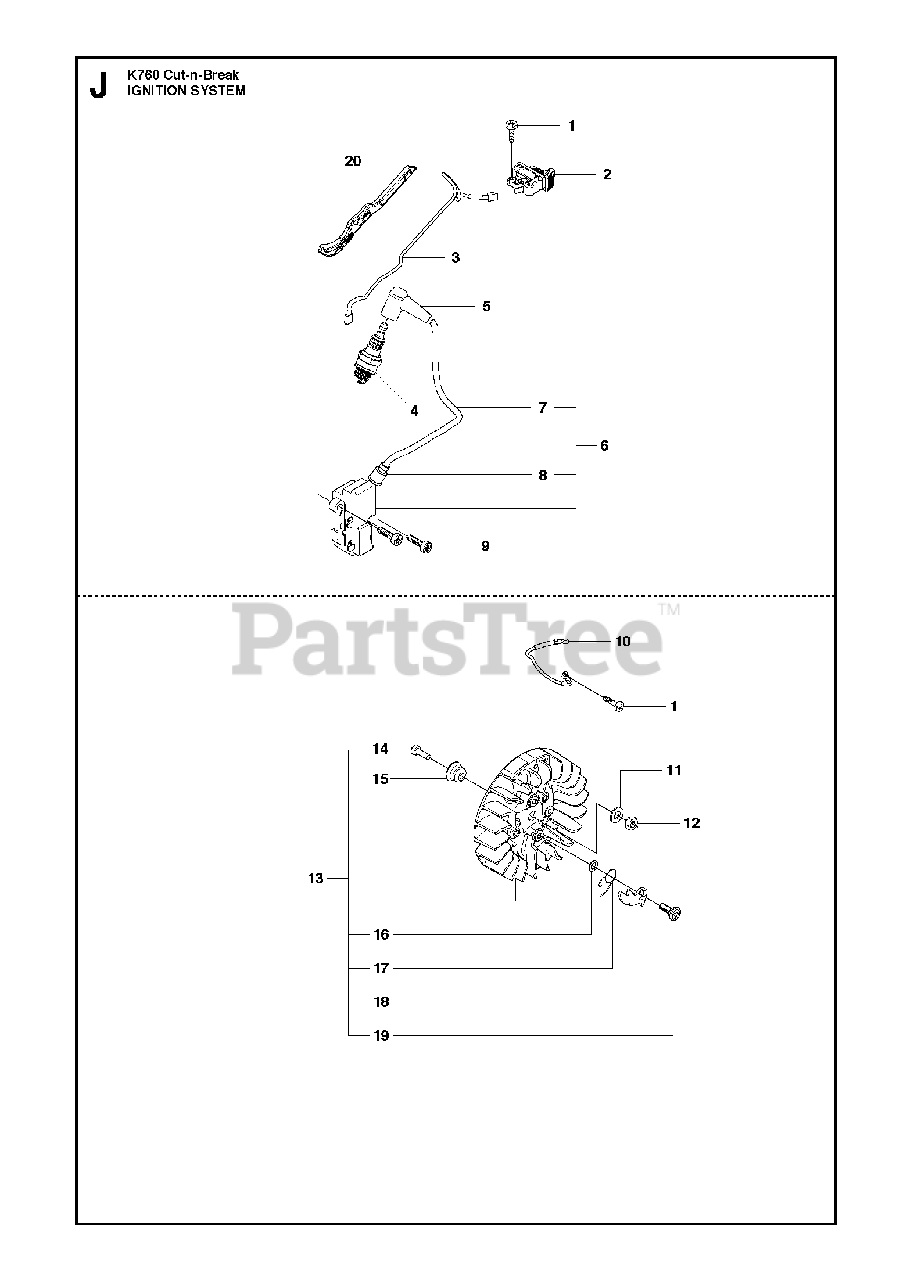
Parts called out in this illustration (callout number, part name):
1	SCREW CCRPANT
2	STOP SWITCH
3	CABLE
4	SPARK PLUGRCJ 6 Y
5	SPARK PLUG CAP
6	IGNITION MODULEIncl. 7 - 8
7	IGNITION CABLE
9	SCREW ITXSCM
13	FLYWHEELIncl. 14 - 19
14	SCREW IHSCM
19	SCREW
20	CABLE HOLDER
